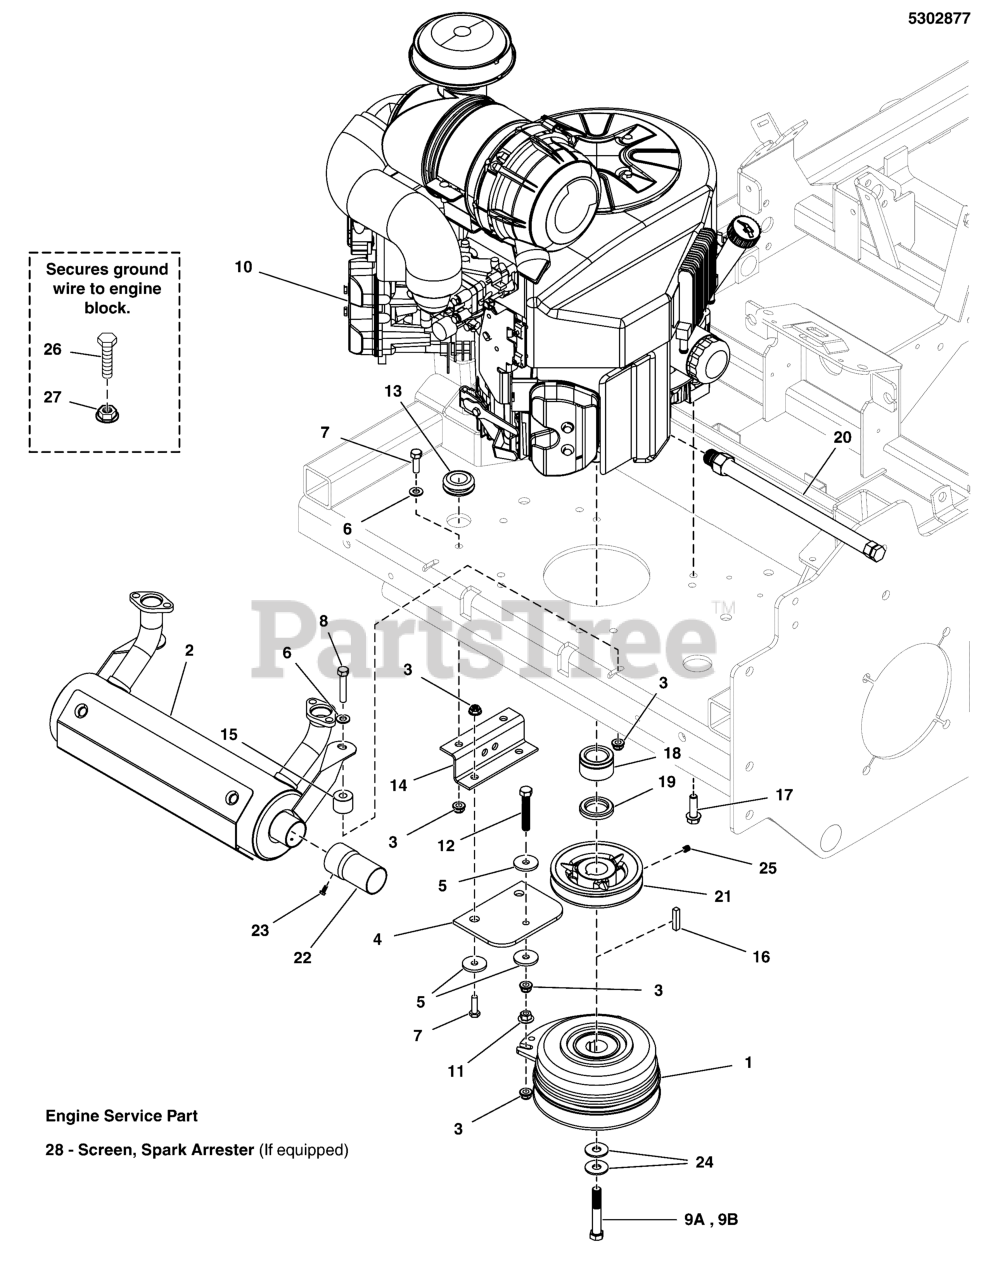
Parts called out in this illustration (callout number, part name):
1	* CLUTCH, WARNER, 200 ft lbs - 1.13"
2	MUFFLER, 27HP KAWASAKI, 5" CAN
3	NUT, 5/16-18 HEX NYLOCK FLANGE
4	CLUTCH ANCHOR PAD
5	WASHER, .34 X 1.25 X 10 GA
6	WASHER, 5/16" SAE
7	BOLT, 5/16-18 X 1 GD5 CZ
8	BOLT, 5/16-18 X 1-3/4 GD5 CZ
9A	** BOLT, CRANKSHAFT,7/16-20X2-3/4, GD8
9B	** BOLT, CRANKSHAFT,7/16-20X2-1/2, GD8
10	ENGINE, 26HP KAWA, FX801V
11	NUT, 5/16-18 HEX SERRATED FLANGE (LARGE)
12	BOLT, 5/16-18 X 2-1/4 TFL, GD5 YZ
13	GROMMET, 7/8"ID, 1/4" THICK STK
14	ANCHOR, CLUTCH - BLK
15	SPACER, .39 X 1.00 X .80, CZ
16	KEY, 1/4 SQ X 1-1/4
17	BOLT, 3/8-16 X 1-1/4, SF, PLT W/PATCH
18	SPACER, 1.13 X 1.75 X 1.03, CZ
19	SPACER, 1.13 X 1.75 X .25
20	HOSE, OIL DRAIN, M20 X 2.5
21	PULLEY, 4.75 OD X 1-1/8 BORE, BC-48
22	EXTENSION, TAILPIPE, 3"
23	SCREW,SELF-TAP,#8-32 X 3/8,WASH HEX, CZ
24	BELLEVILLE WASHER 1.1875 X .442 X .089
25	SET SCREW, 5/16-18 X 3/8, KNURL, W/PATCH
26	BOLT, M8-1.25 X 20 MM GD8.8
27	NUT, M8-1.25 SERR. FLANGE, CZ
28	SCREEN, SPARK ARRESTER
